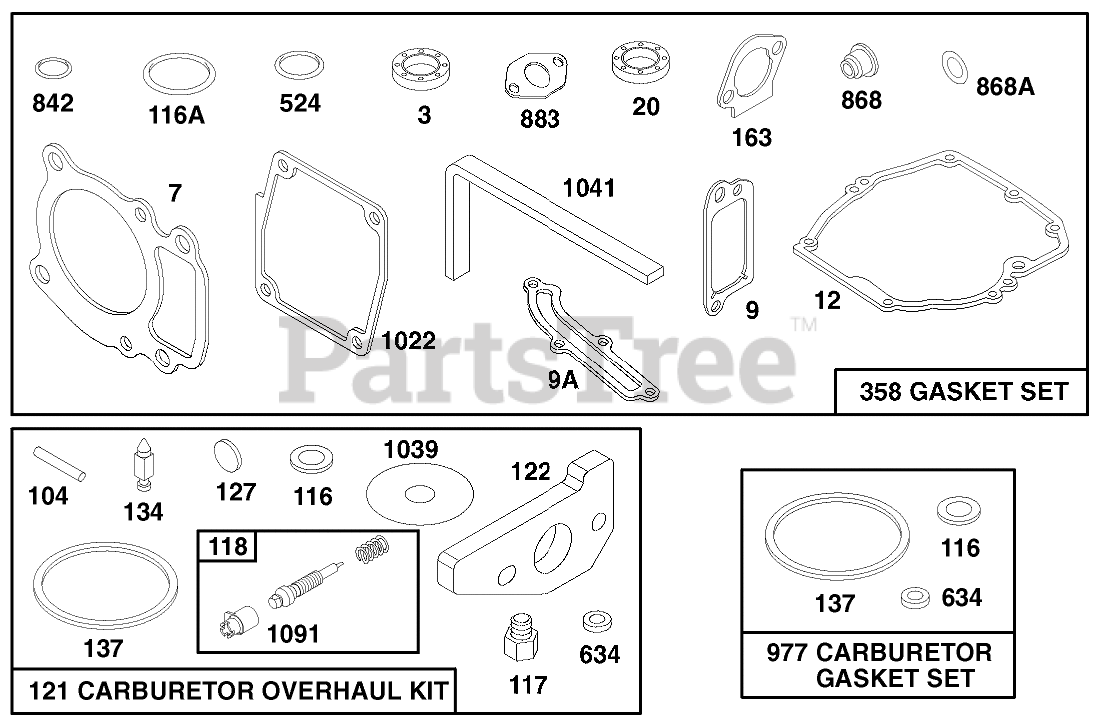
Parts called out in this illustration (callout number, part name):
3	SEAL - OIL
7	CYLINDER HEAD GASKET
9	BREATHER GASKET
9A	GASKET-BREATHER
12	ENGINE BASE GASKET
20	SEAL-OIL
37	GUARD - FLYWHEEL
104	FLOAT HINGE PIN
116	SEALING GASKET
116A	O RING SEAL
117	Jet-Main
118	VALVE/SPRING - NEEDLE
121	KIT-CARBURETOR OVERHAUL
122	ADAPTER ASSEMBLY
127	PLUG - WELCH
134	Valve-Inlet(Includes Seat)
137	FLOAT BOWL GASKET
163	AIR CLEANER GASKET
358	GASKET SET
524	O-RING
634	SEAL WASHER
842	O-RING
868	SealAssy-Valve
868A	Seal-Valve
883	EXHAUST GASKET
977	CARBURATOR GASKET SET
1022	ROCKER COVER GASKET
1039	FLOAT LIMITER
1041	SEAL - FOAM
1091	CAP - LIMITER
